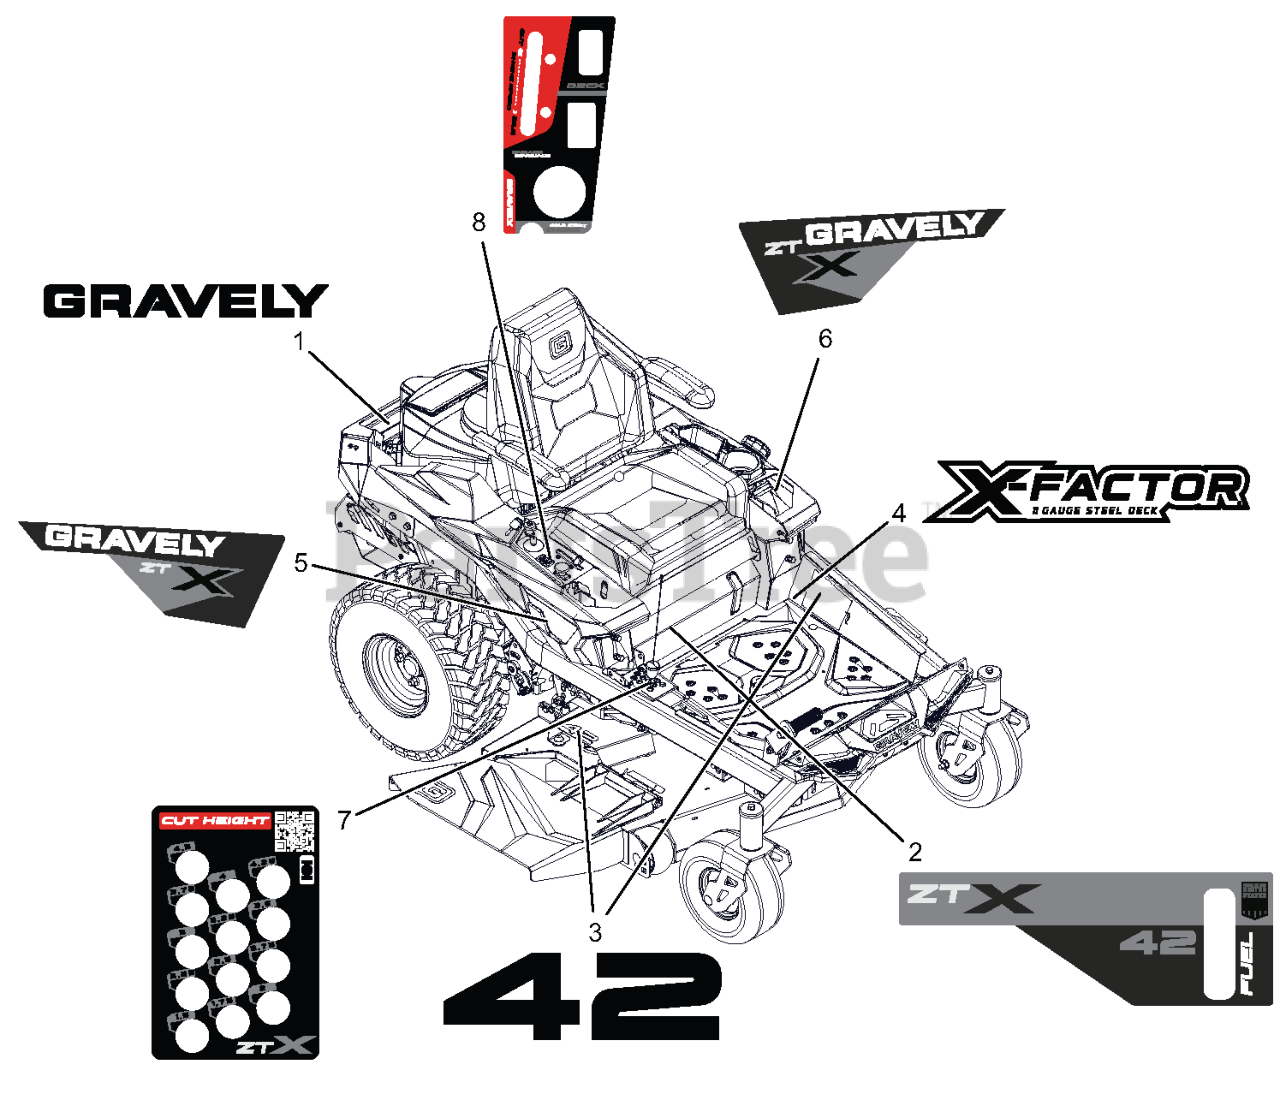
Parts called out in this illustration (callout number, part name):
1	DECAL- GRAVELY
2	DECAL- ZTX 42-KICK PLATE
3	DECAL- DECK 42"
4	DECAL- DECK X-FACTOR
5	DECAL- ZT X FENDER RH
6	DECAL- ZT X FENDER LH
7	DECAL- HEIGHT OF CUT-X
8	DECAL- CONTROL PANEL-GRAVELY
